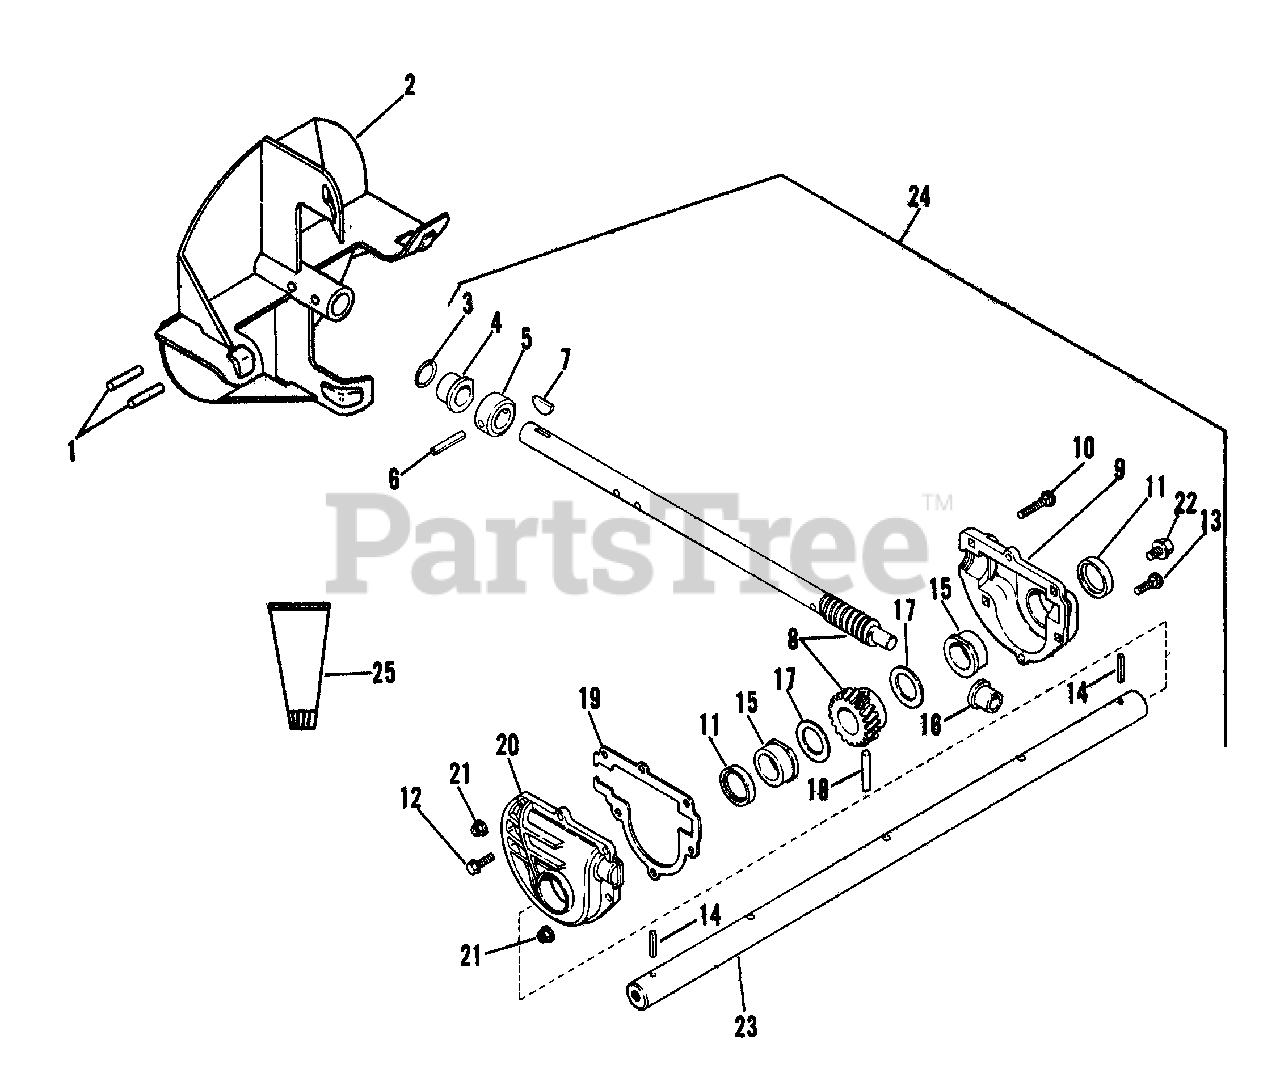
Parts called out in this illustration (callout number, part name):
1	PIN-ROLL .250X1.75
2	FAN - 12"
3	O-RING .250X.943X.103
4	BSHG-FLG .750X1.000X.750X1.250
5	THRUST COLLAR
6	PIN-GRV .188X1.25 TP A
7	KEY-WDRF .188X.875X.375 SAE11
8	WORM SHAFT & GEAR ASSY
9	GEAR CASE HALF L H
10	BLT-RDHDSQNK .25-20X1.25 GR5PL
11	SEAL 1.000X1.312X.150
12	SCR-TAP 10-24X.75 HWH PL TR
13	BLT-RDHDSQNK .25-20X.88 PL
14	PIN-ROLL .188X1.50
15	BSHG-FLG1.000X1.12X.62X1.50BR
16	BSHG-FLG .500X.750X.750X1.000
17	WSHR-HRD-THRS 1.007X1.542X.062
18	PIN-GRV .313X1.44 TP C
20	GEAR CASE HALF R H
21	NUT-LK-FLG .250-20 PL
22	SCR-TAP .375-16X .50 HWH PL TR
23	SHAFT, RAKE - 24"
24	GEAR CASE - 24" - ALUMINUM
25	8 OZ TUBE OF LIQUID GREASE
